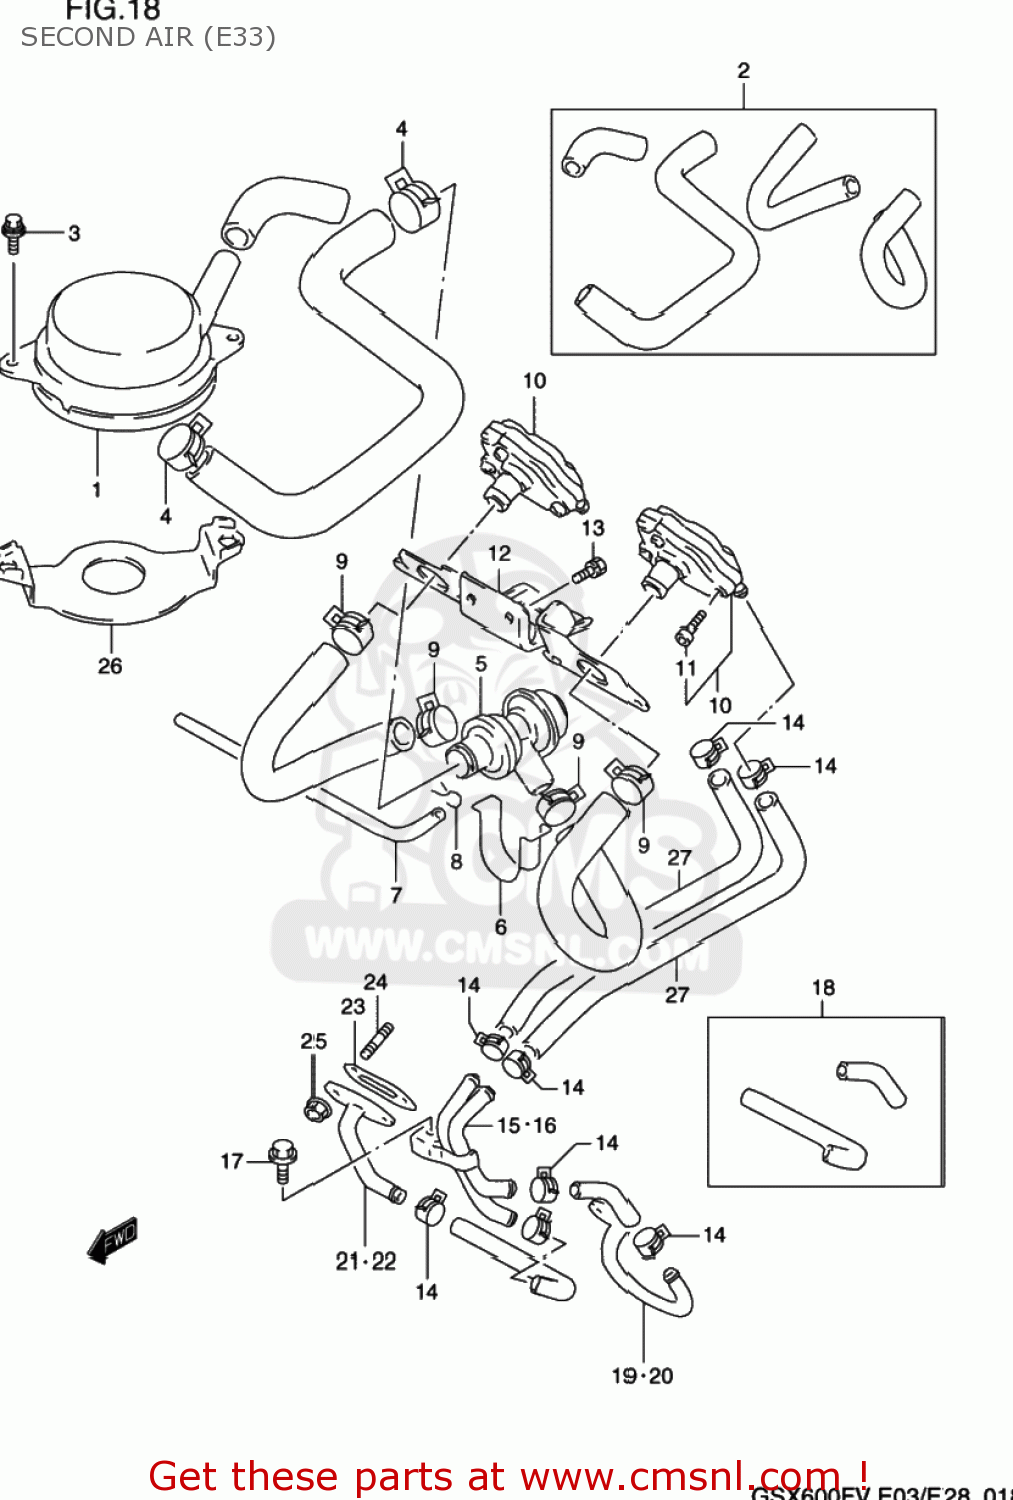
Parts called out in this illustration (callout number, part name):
1	CLEANER ASSEMBLY,SECOND AIR
2	HOSE SET,SECOND AIR NO.2
3	BOLT
4	CLIP
5	VALVE ASSY,AIR SWITCHING
6	CLAMP,SWITCHING VALVE
7	HOSE(4.5X8.5X600)
8	CLAMP
9	CLIP
10	VALVE ASSY,2ND AIR REED
11	BOLT
12	(CA) B/K REED VALVE
13	BOLT
14	CLIP
15	PIPE,SECOND AIR,RIGHT
16	PIPE,SECOND AIR,LEFT
17	BOLT
18	HOSE SET,SECOND AIR NO.1
19	(CA) PIPE,SECOND AIR NO.1
20	(CA) PIPE,SECOND AIR NO.4
21	PIPE,2ND AIR NO.2
22	PIPE,2ND AIR NO.3
23	GASKET,SECOND AIR PIPE (NAS)
24	STUD BOLT
25	NUT
26	HOLDER,SECOND AIR CLEANER
27	HOSE,SECOND AIR NO.1,INLET
